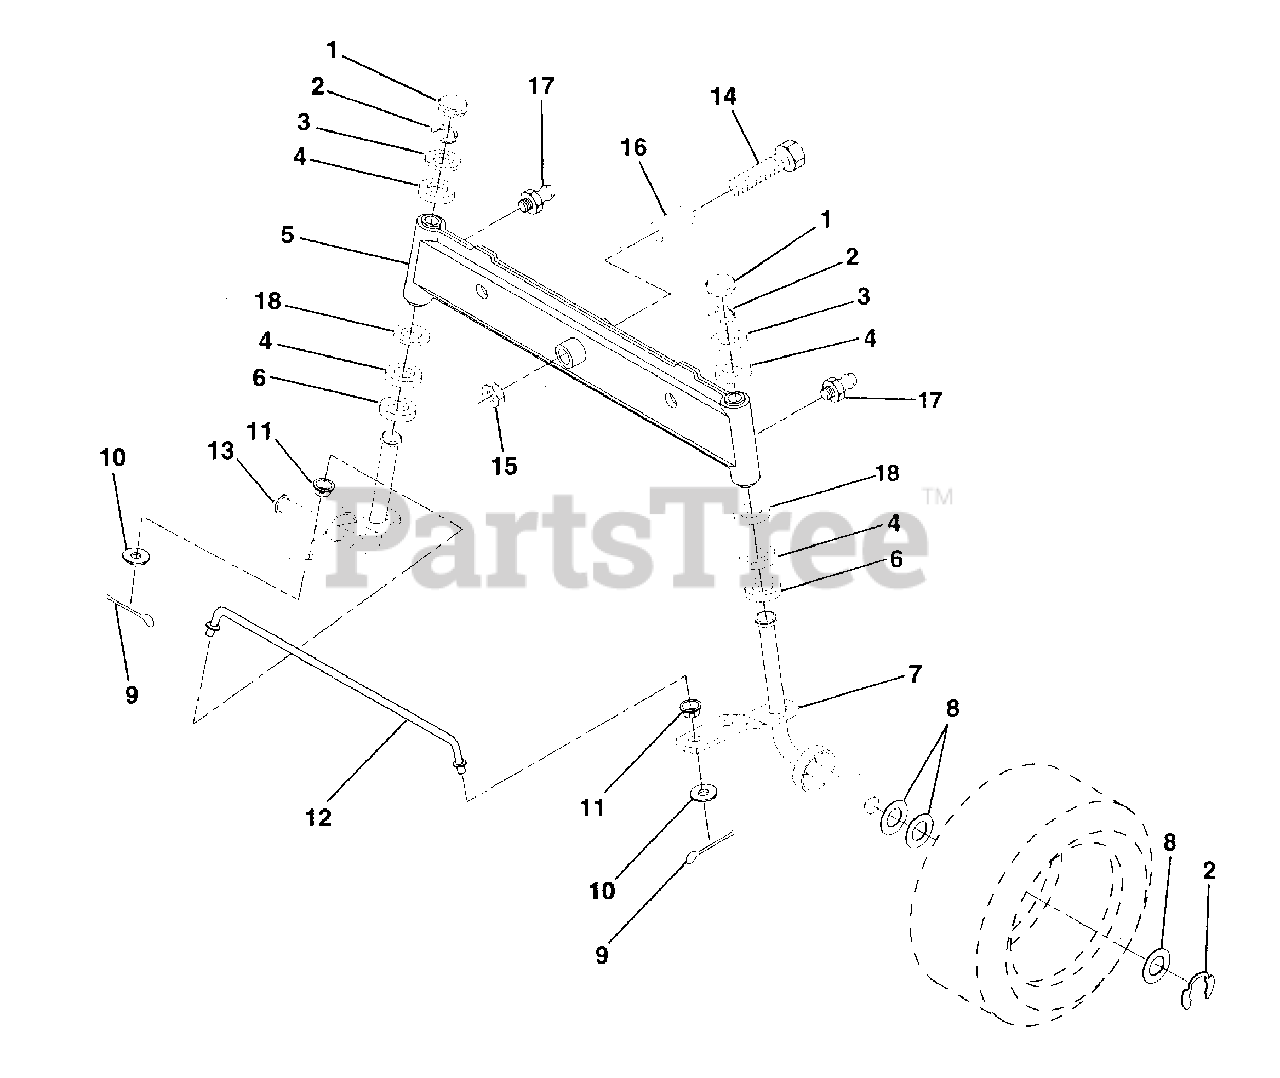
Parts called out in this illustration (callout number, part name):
1	Cap, Spindle
2	Ring, Clip
3	Washer 25/32 x 1-5/8 x 16 Ga.
4	Nyliner
5	Axle, Front
6	Bearing, Thrust
7	Spindle, R.H. Asm.
8	Washer 25/32 x.1-1/4 x 16 Ga.
9	Pin, Cotter 1/8 x 3/4
10	Washer 13/32 x 13/16 x 16 Ga.
12	Rod, Tie
13	Spindle, L.H. Asm.
14	Bolt Hex 5/1-11 x 3-1/2
15	Nut, Lock Flange 5/8-11
16	Spacer Bearing Axle
17	Fitting Grease
18	Washer 27/32 x 1-1/4 x 16 Ga.
